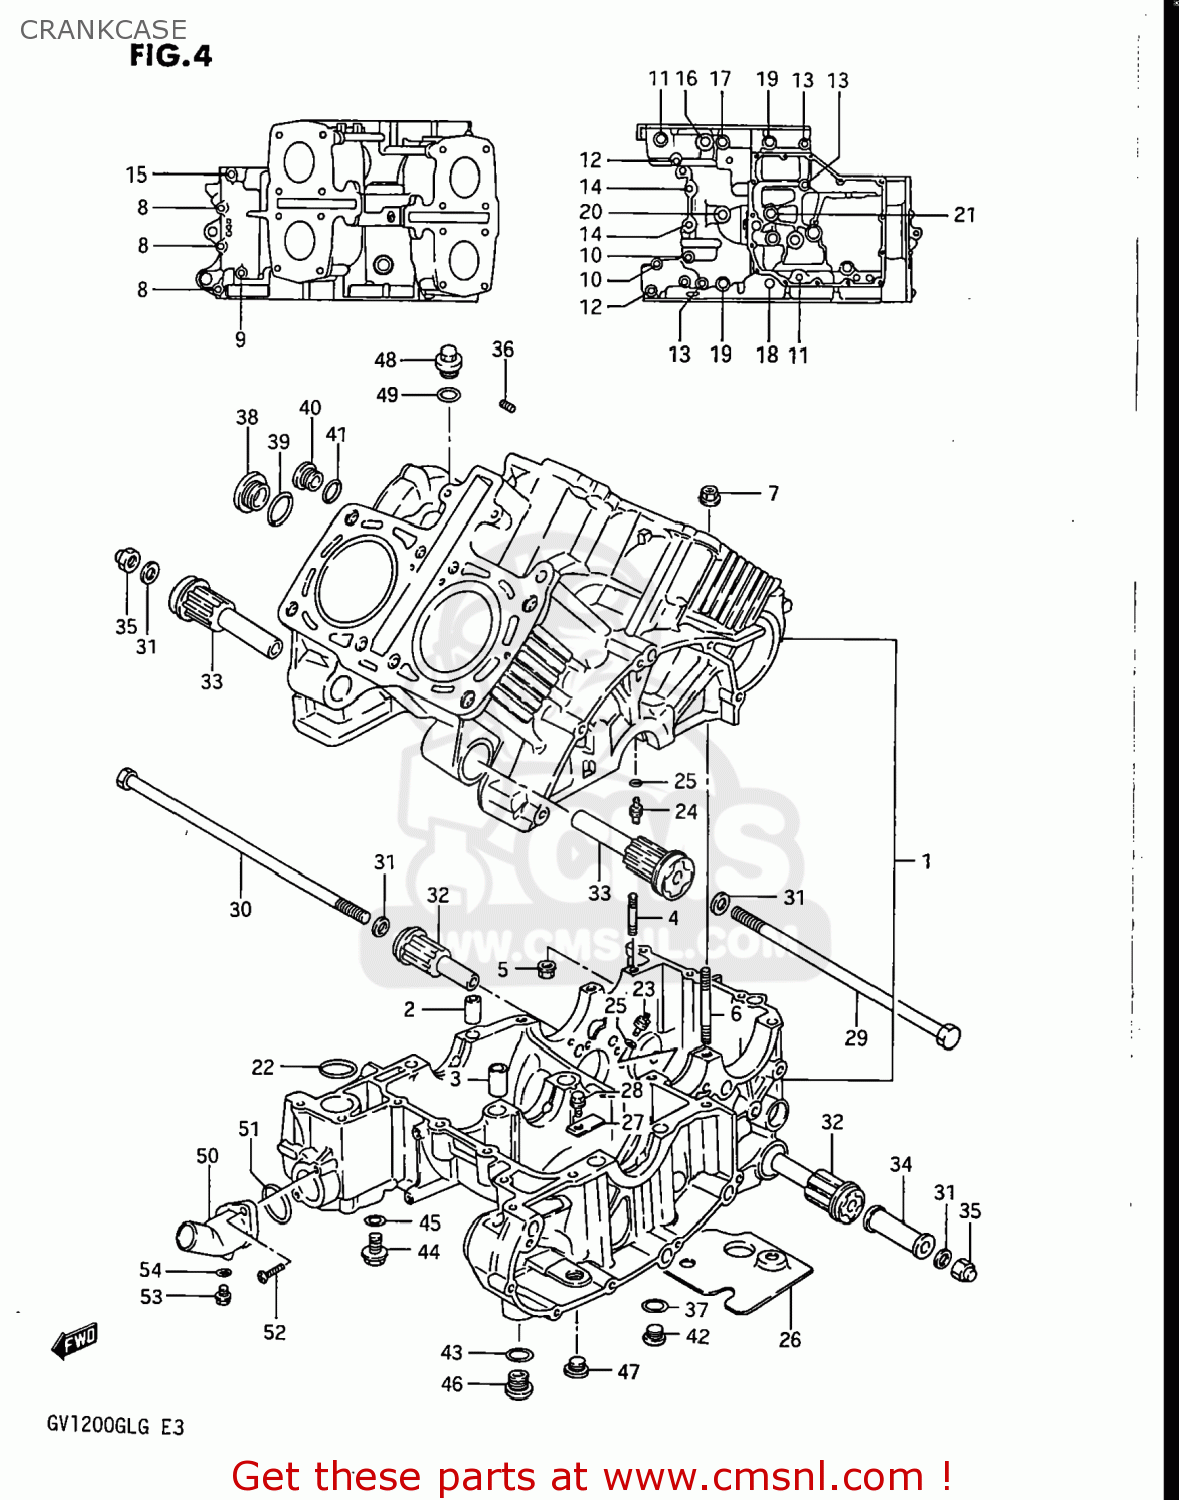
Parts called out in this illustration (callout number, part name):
1	CRANKCASE SET
2	PIN(10.4X13X22)
3	PIN
4	STUD 6X50
5	NUT
6	STUD BOLT
7	NUT 8MM
8	BOLT 6X35
9	BOLT
10	BOLT (6X90)
11	BOLT
12	BOLT(6X100)
13	BOLT
14	BOLT
15	BOLT 8X60
16	BOLT 8X35
17	BOLT L:140
18	BOLT(10X150)
19	BOLT
20	BOLT
21	BOLT
22	O-RING (D:3 ID:27)
23	JET,OIL GALLERY
24	JET,OIL GALLERY(16)
25	O RING(D:1.2,ID:4)
26	PLATE,OIL SEPARATOR
27	MAGNET, DUST CATCH
28	BOLT
29	BOLT
30	BOLT 10X305
31	WASHER
32	BUSHING,ENGINE MOUNTING,REAR
33	BUSHING,ENGINE MOUNT
34	SPACER,ENGINE MOUNT(L:65)
35	NUT
36	PLUG
37	GASKET(16X22X2) (NAS)
38	PLUG
39	O-RING
40	PLUG
41	O RING(D:3.1,ID:16.8)
42	PLUG
43	GASKET(14X19.2X2) (NAS)
44	BOLT
45	GASKET(10.1X16X1) (NAS)
46	PLUG
47	PLUG
48	PLUG
49	O RING(D:3.1,ID:16.8)
50	CONNECTOR,WATER INLET
51	O RING(D:2.4,ID:31.7)
52	SCREW
53	BOLT,DRAIN
54	GASKET 8.2X14X1 (NAS)
